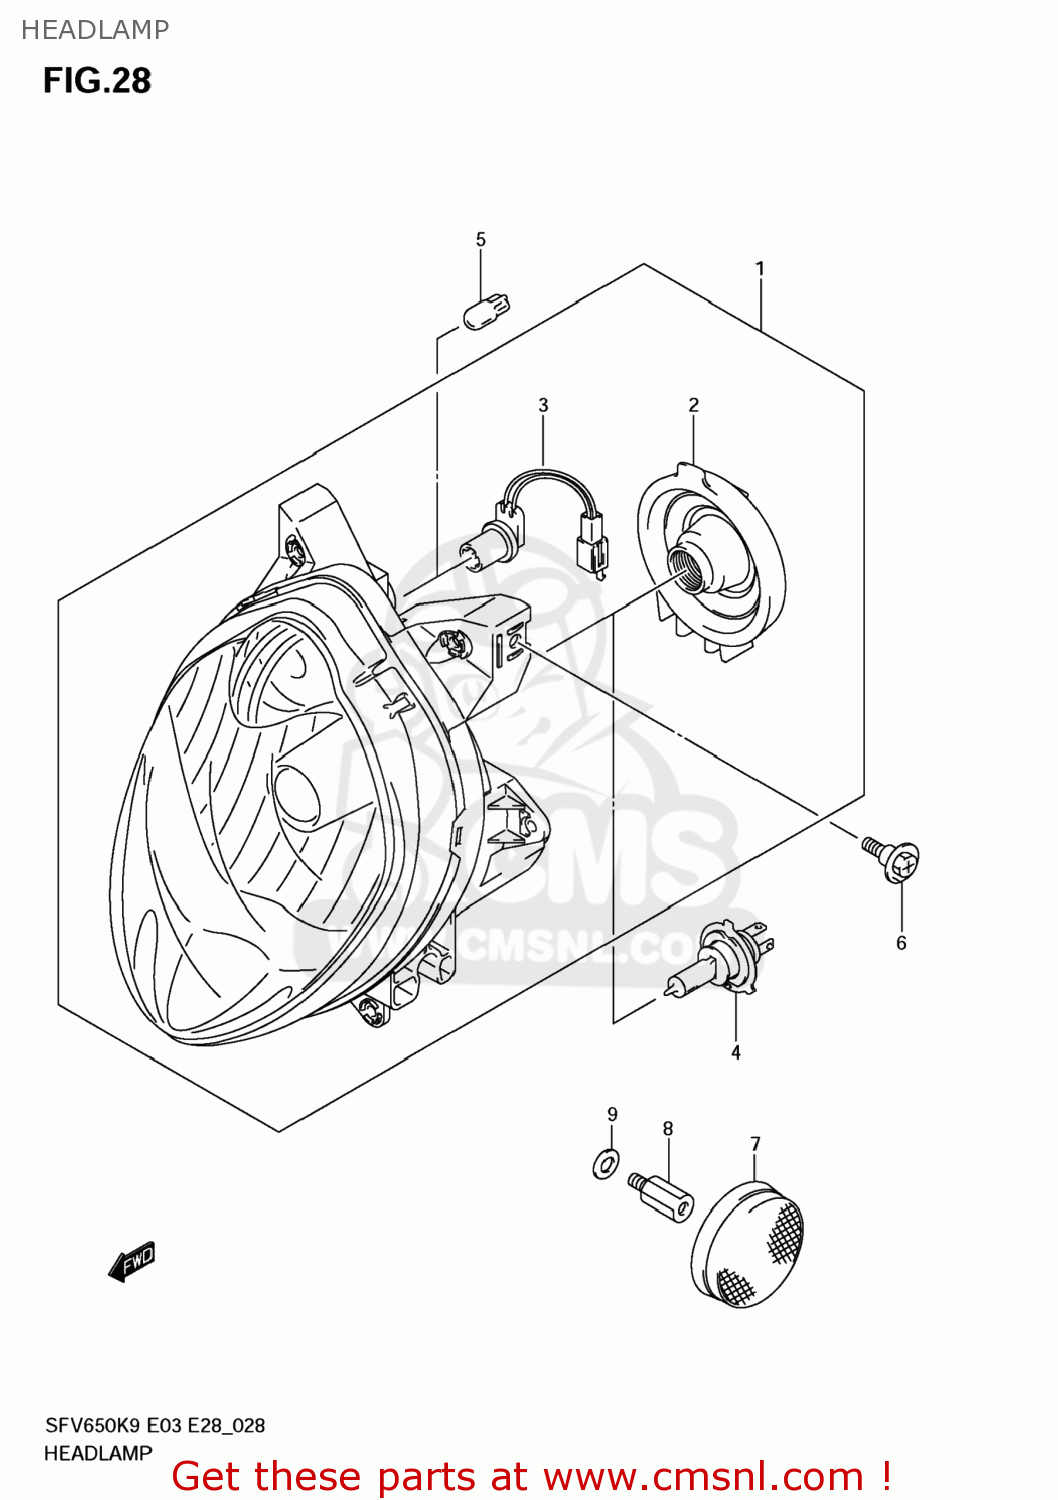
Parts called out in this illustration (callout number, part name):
1	HEADLAMP ASSY
2	COVER,SOCKET
3	KABEL.VERLICHTI
4	BULB(12V60/55W,H4)
5	BULB(12V5W)
6	SCREW(6X22.5)
7	REFLECTOR,REFLEX
8	BOLT(5X10)
9	WASHER
